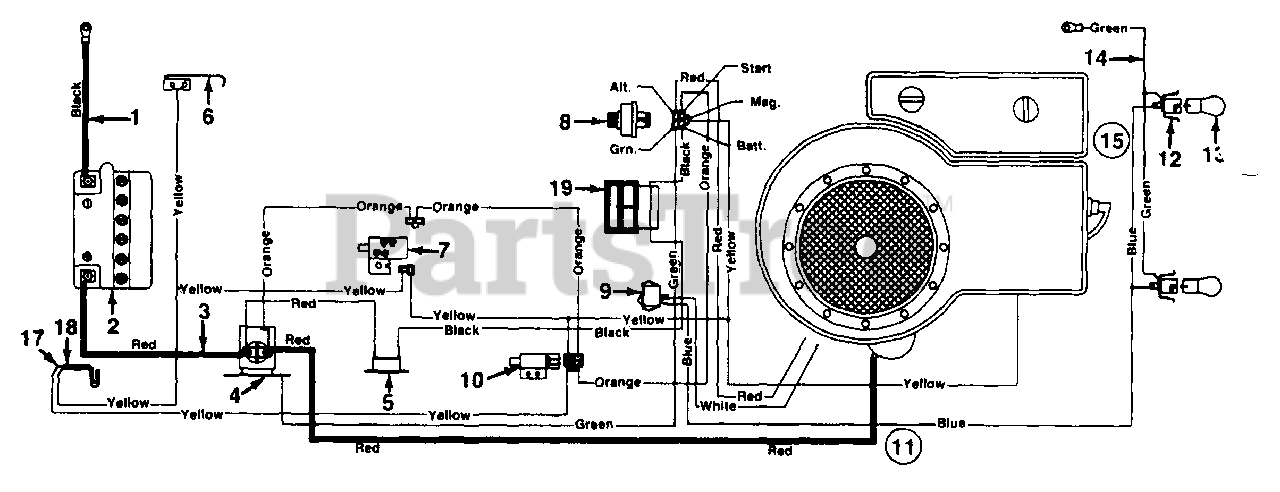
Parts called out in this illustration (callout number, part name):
2	Battery
3	Electric Wire
4	Solenoid
5	Circuit Breaker
6	Spring Switch (Reverse)
7	Safety Switch (Deck)
8	Ignition Switch
9	Light Switch
10	Safety Switch (Clutch)
11	Harness (B&S)
12	Socket
13	Bulb
15	Headlight Harness
17	Safety Switch (Seat)
18	Safety Switch (Seat)
19	Ammeter
